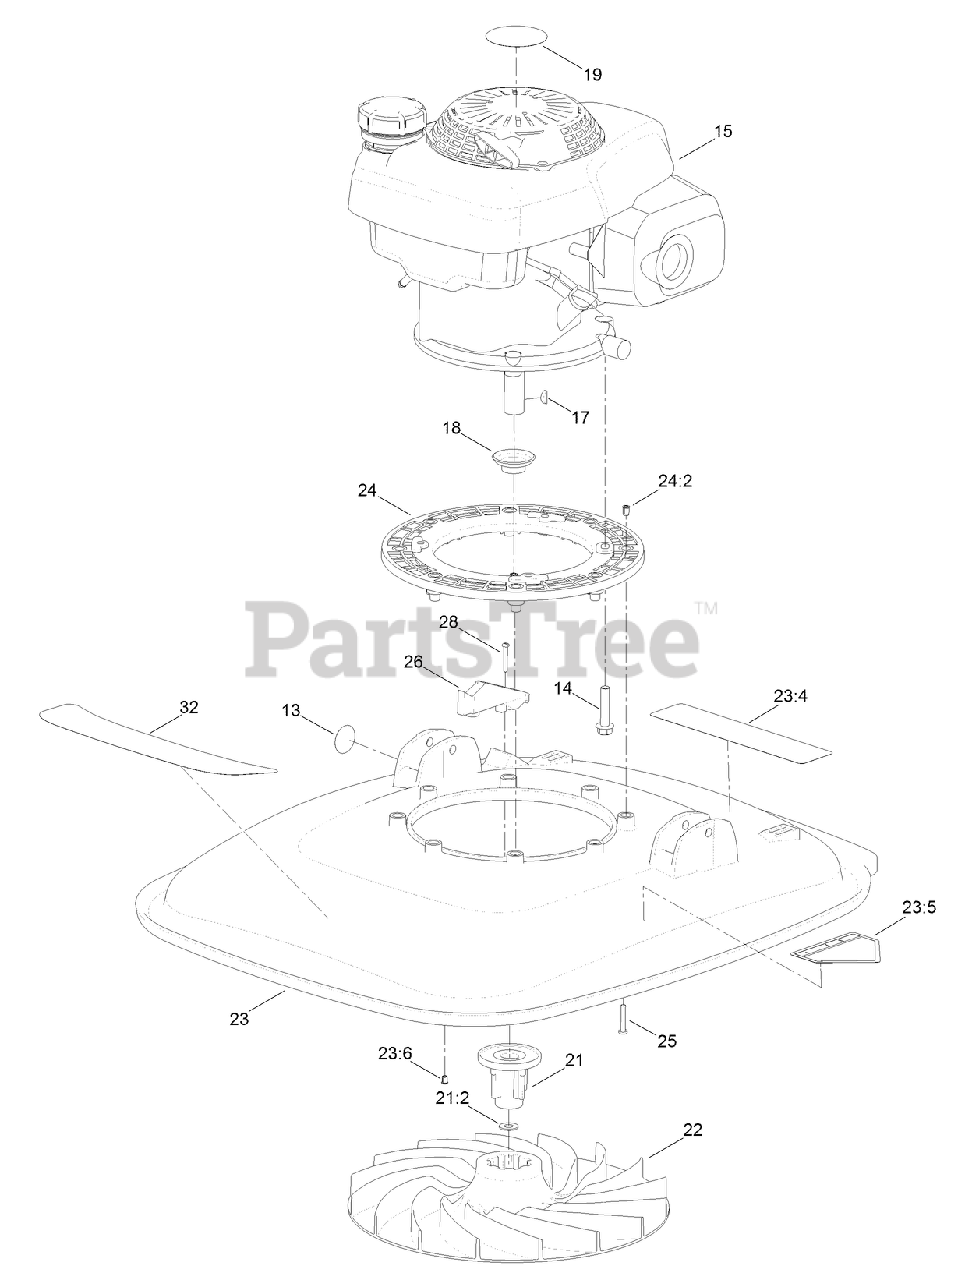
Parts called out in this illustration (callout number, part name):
13	DECAL
14	SCREW-TAPTITE
15	ENGINE-HONDA
17	KEY-WOODRUFF
18	PROTECTOR-SEAL, OIL
19	DECAL-ENGINE
21	DRIVE AND SPACER ASM
21:2	WASHER-PLAIN
22	IMPELLER
23	DECK ASM
23:4	DECAL-WARNING
23:5	DECAL-DANGER
23:6	INSERT
24	FRAME-ENGINE
24:2	INSERT-BRASS
25	SET-SCREW
26	BRACKET
28	SCREW
32	DECAL-HOVER PRO, 500 SERIES
